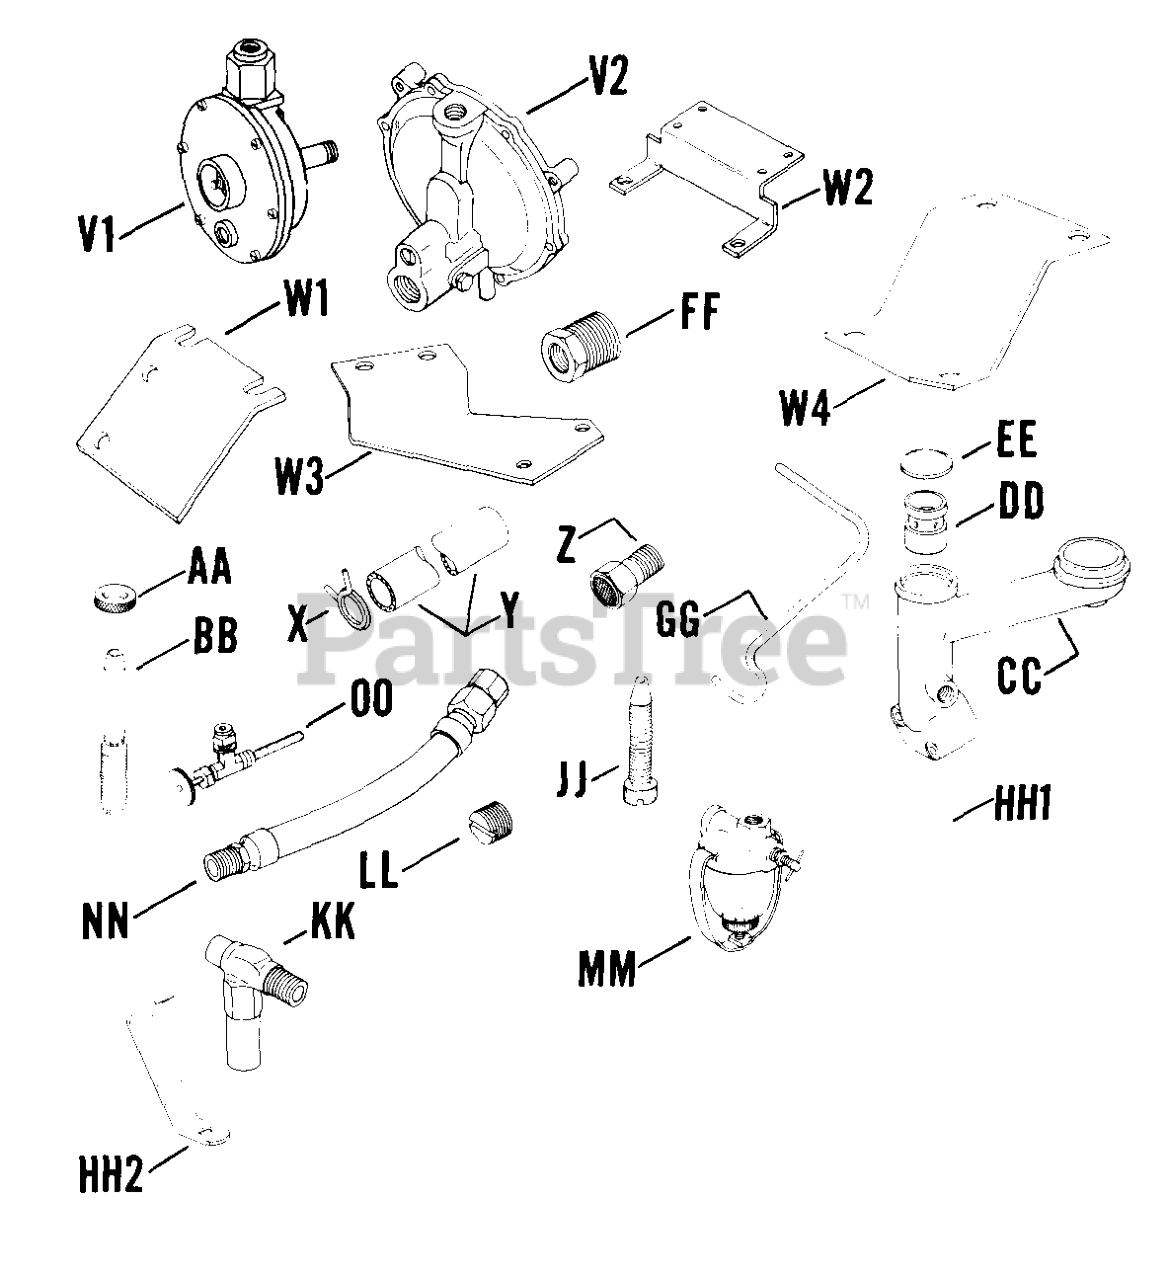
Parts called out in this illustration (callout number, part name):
X	USE X-426-3-S
DD	Venturi
JJ	Valve, needle
KK	Body, valve
